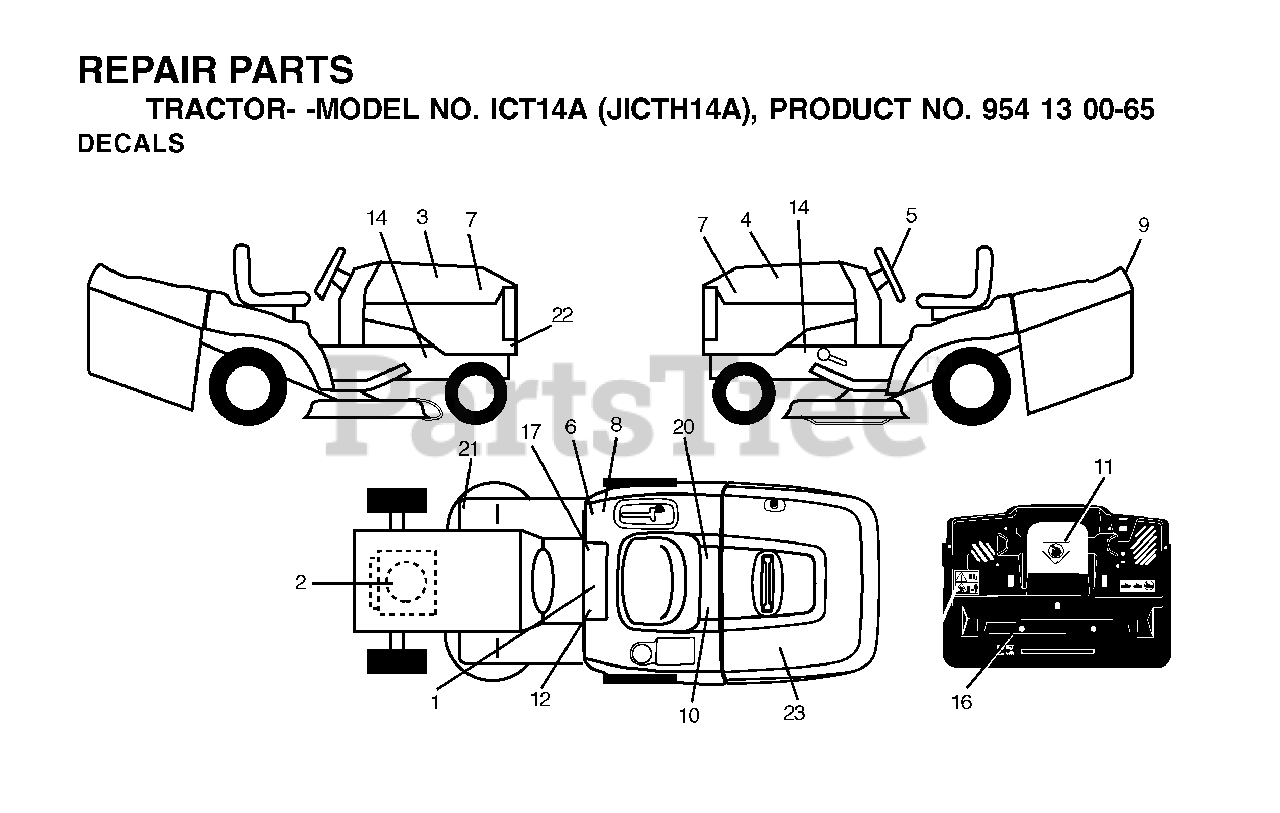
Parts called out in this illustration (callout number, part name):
1	DECAL READ OWNER'S MAN SYMS
6	DECAL CERTIFICATION
8	DECAL EUROPE STANDARD CE
10	DECAL BTRY SYMBOLS
11	DECAL MOWER CUT/FINGER
17	DECAL PARK BRAKE
20	DECAL.BYPASS.FENDER.CRD.LT.YT
